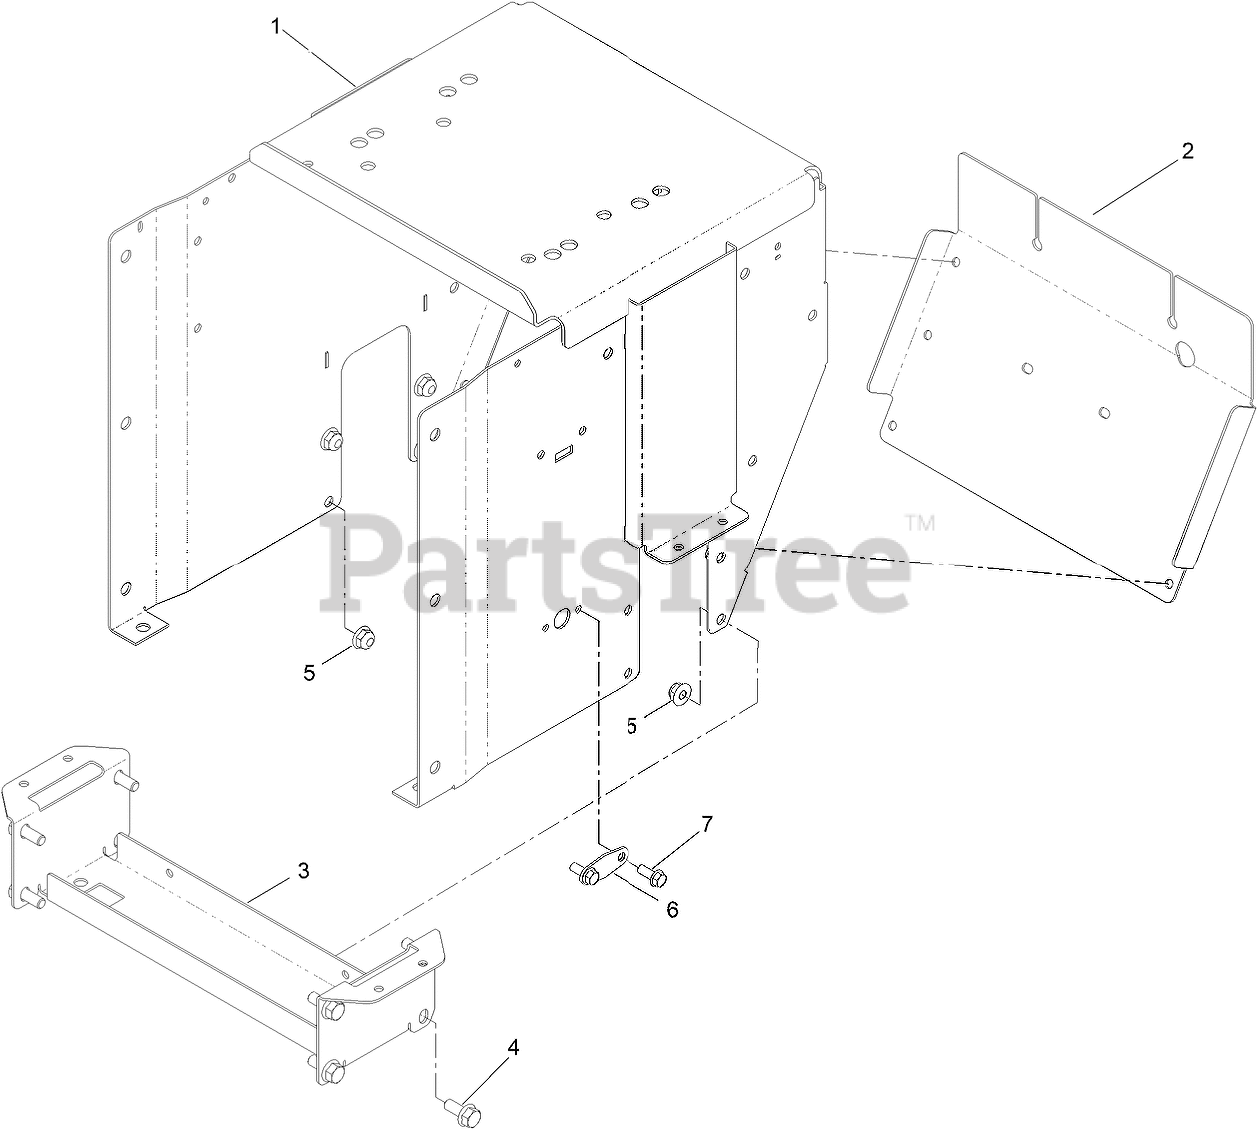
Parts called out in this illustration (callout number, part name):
1	FRAME-TRACTION
2	COVER-REAR
3	BRACE-FRAME, LOWER
4	SCREW-HHF
5	NUT-HF
6	COVER-LOCK, NEUTRAL
7	SCREW-HWH
